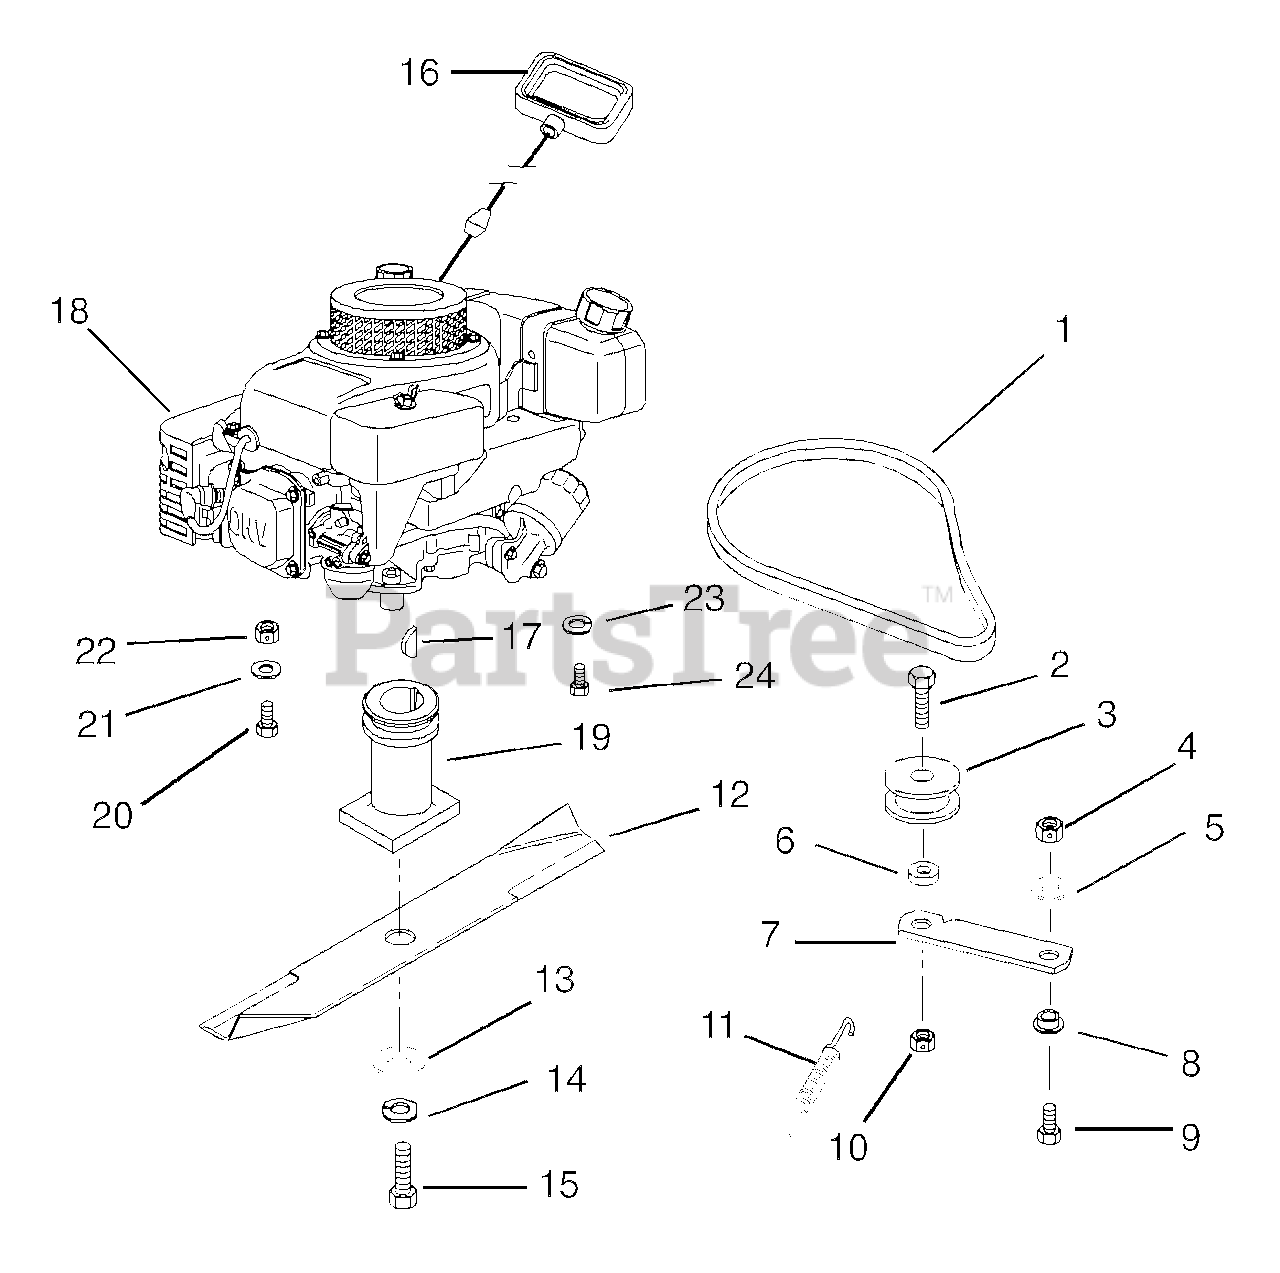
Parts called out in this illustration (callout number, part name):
2	Bolt-Hex .44-14 x 1.25 Grade 5
3	Idler-Flat 1.75 x .47
4	Nut-Locking-Center .31 -18
5	Washer-Flat-Steel .323 x .625 x .062
6	Spacer .52 x .45 x .34
7	Idler Arm
8	Bushing-Flange .325 x .501 x .250 x 1.120
9	Bolt-Hex .31-18 x .75 Grade 5
10	Nut-Locking-Center .44-14
11	Spring, Tension .043 x .44 x 3.31
12	Blade, 21" Mower
12	Blade, 21" Mower Tungsten
13	Washer-Flat Steel .390 x 1.50 x .125
14	Washer-Locking .38 x .094
15	Bolt, Hex .38-24 x 2.00 Grade 8
16	Recoil Start Handle
17	Key-Woodruff .156 x .625 x .25
18	Engine, Robin 6 HP 4 Cycle
19	Blade Adapter
20	Bolt - Hex .31-18 x 1.25 Grade 5
21	Washer-Flat-Steel .312 x .734 x .065
22	Nut-Locking-Center .31-18
23	Washer - Locking .312 x .097 Heavy
24	Bolt-Hex .31-18 x .75 Grade 5
